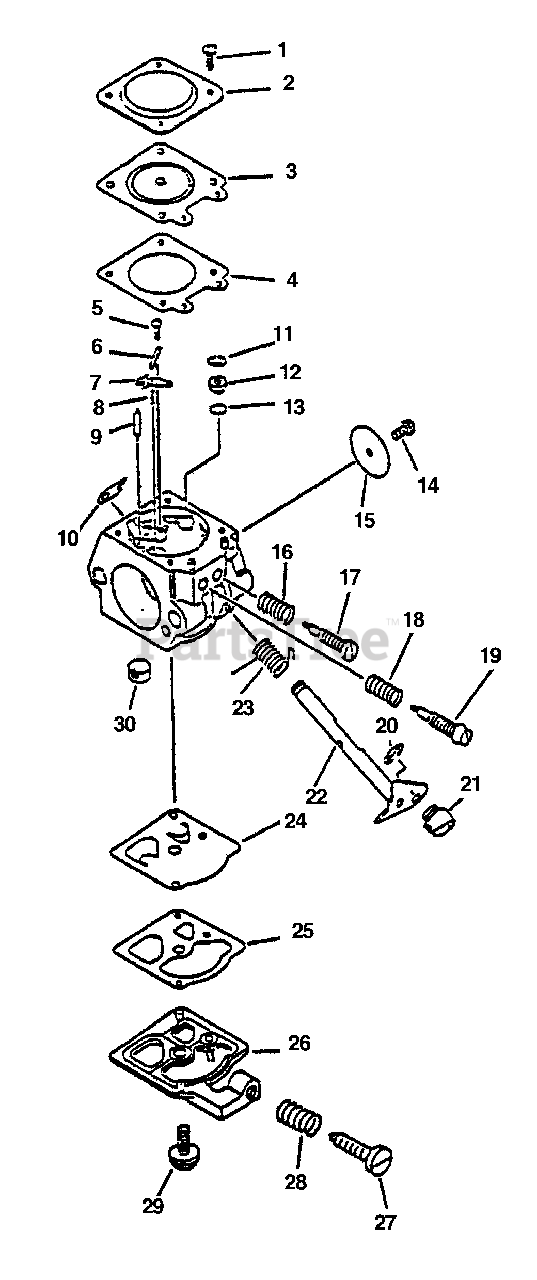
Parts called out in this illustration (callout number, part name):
1	SCREW
2	COVER, METERING
3	DIAPHRAGM, METERING
4	GASKET, METERING
5	SCREW, METERING LEVER PIN
6	PIN, METERING LEVER
7	LEVER, METERING
8	SPRING, METERING LEVER
9	VALVE, NEEDLE
10	RING, RETAINING
11	RING, RETAINING
12	JET - 40
13	O-RING
14	SCREW, VALVE
15	VALVE, THROTTLE
16	SPRING, LOW SPEED NEEDLE
17	NEEDLE - LOW SPEED
18	SPRING, HIGH SPEED NEEDLE
19	NEEDLE - HIGH SPEED
20	RING, RETAINING
22	SHAFT, THROTTLE
23	SPRING, THROTTLE RETURN
24	DIAPHRAGM, PURGE
25	GASKET, PURGE
26	COVER, PUMP
27	SCREW, IDLE ADJUST
28	SPRING, IDLE ADJUST
29	SCREW, PUMP COVER
30	STRAINER
